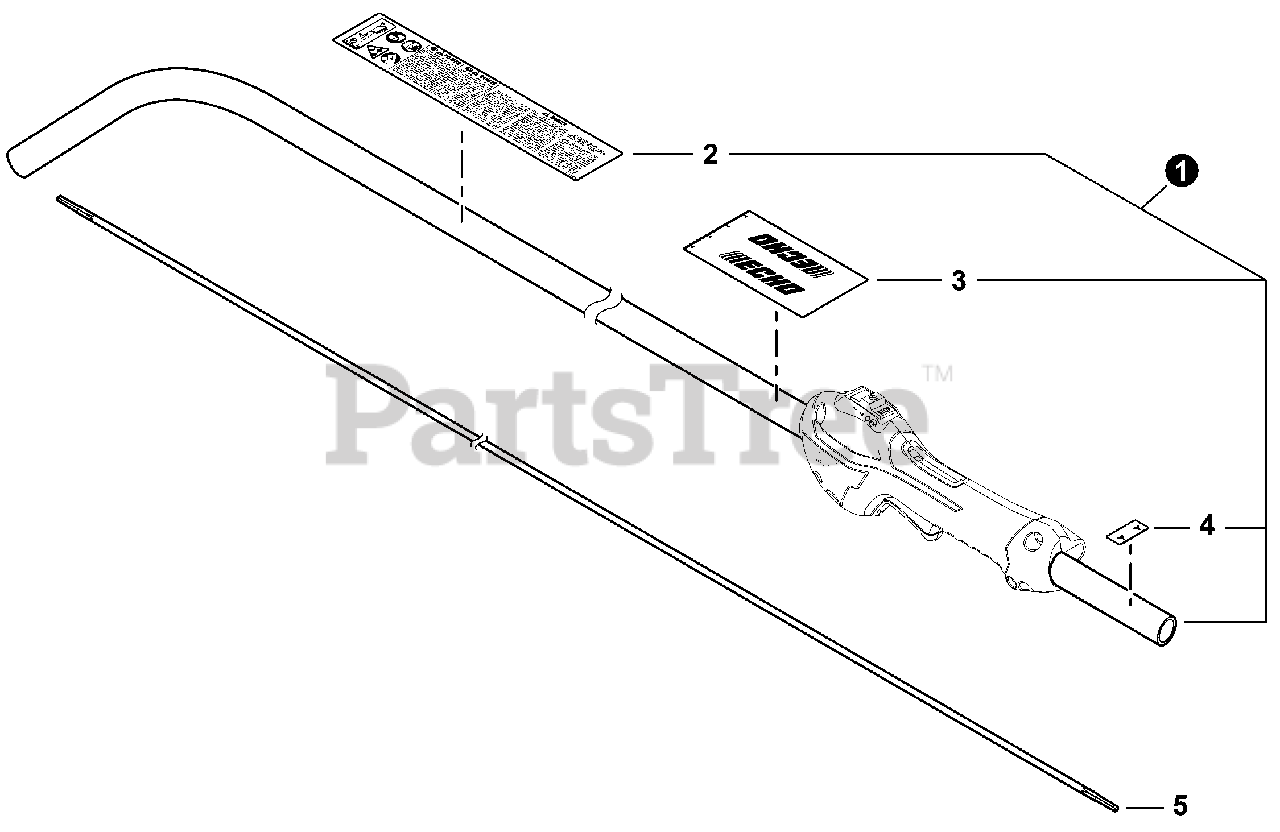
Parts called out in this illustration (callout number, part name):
1	MAIN PIPE ASSY
2	LABEL, CAUTION
3	LABEL, HANDLE LOCATION
4	LABEL - ALIGNMENT
5	DRIVESHAFT - FLEXIBLE
